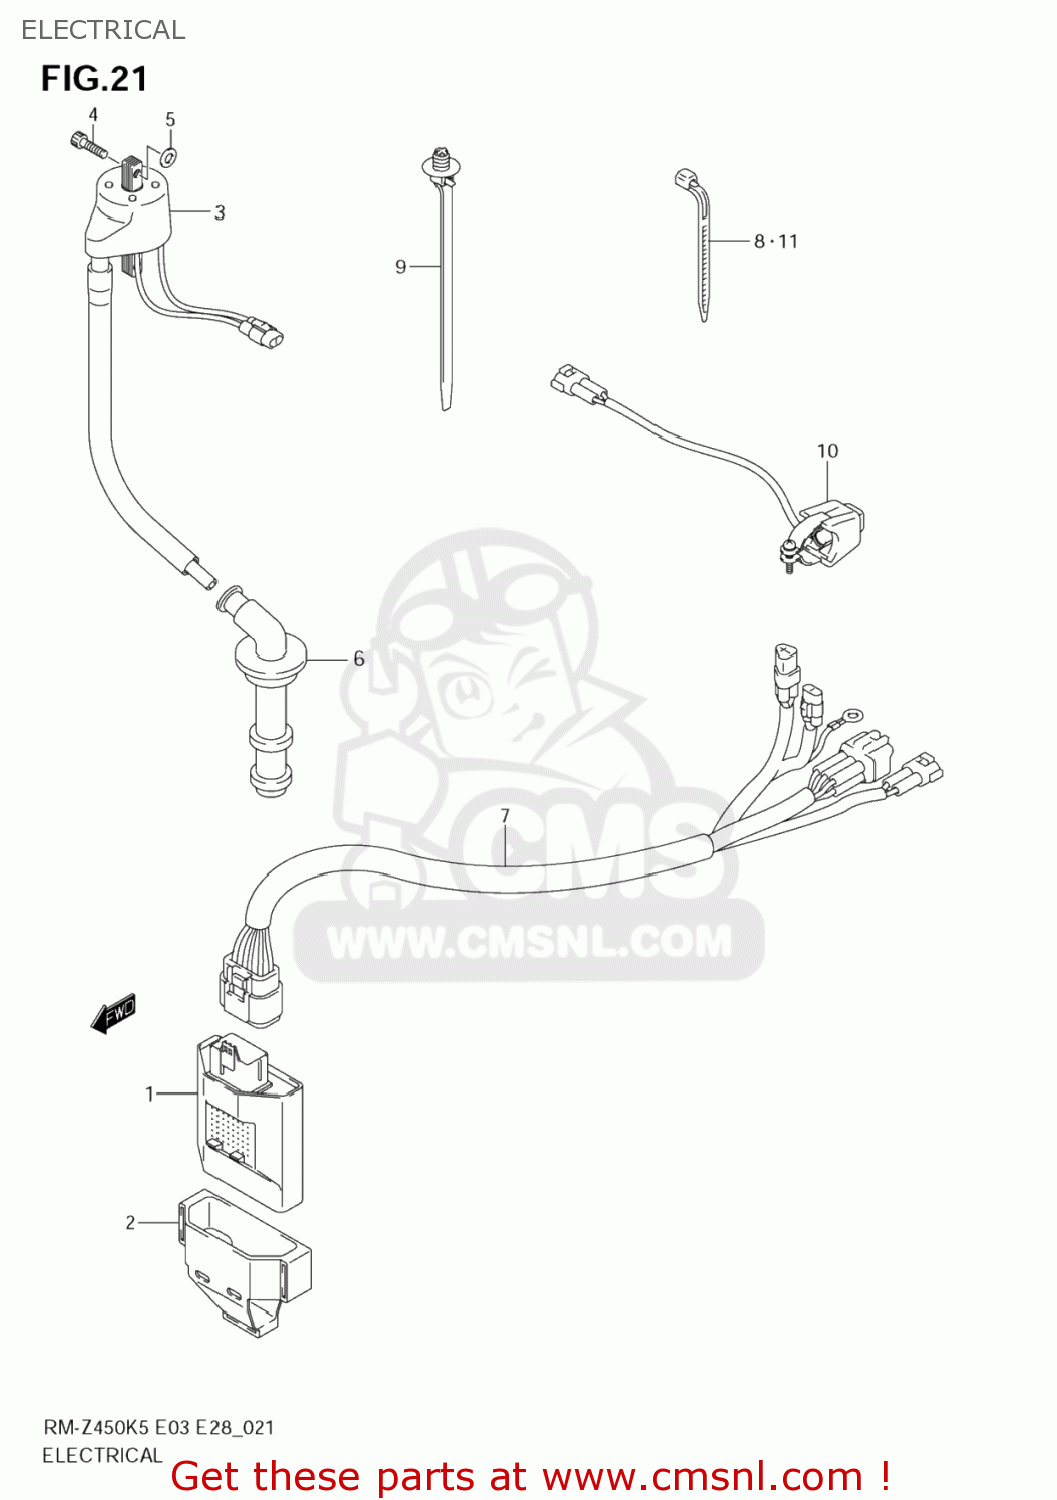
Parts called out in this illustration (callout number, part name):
1	CDI UNIT
2	CUSHION,CDI UNIT
3	COIL ASSY,IGNITION
4	BOLT,CRKCASE,R
5	WASHER(6.5X18X1)
6	CAP ASSY,SPARK PLUG
7	HARNESS,WIRING
8	CLAMP(L:95)
9	CLAMP(L:154)
10	SWITCH ASSY,ENGINE STOP
11	CLAMP(L:95)
